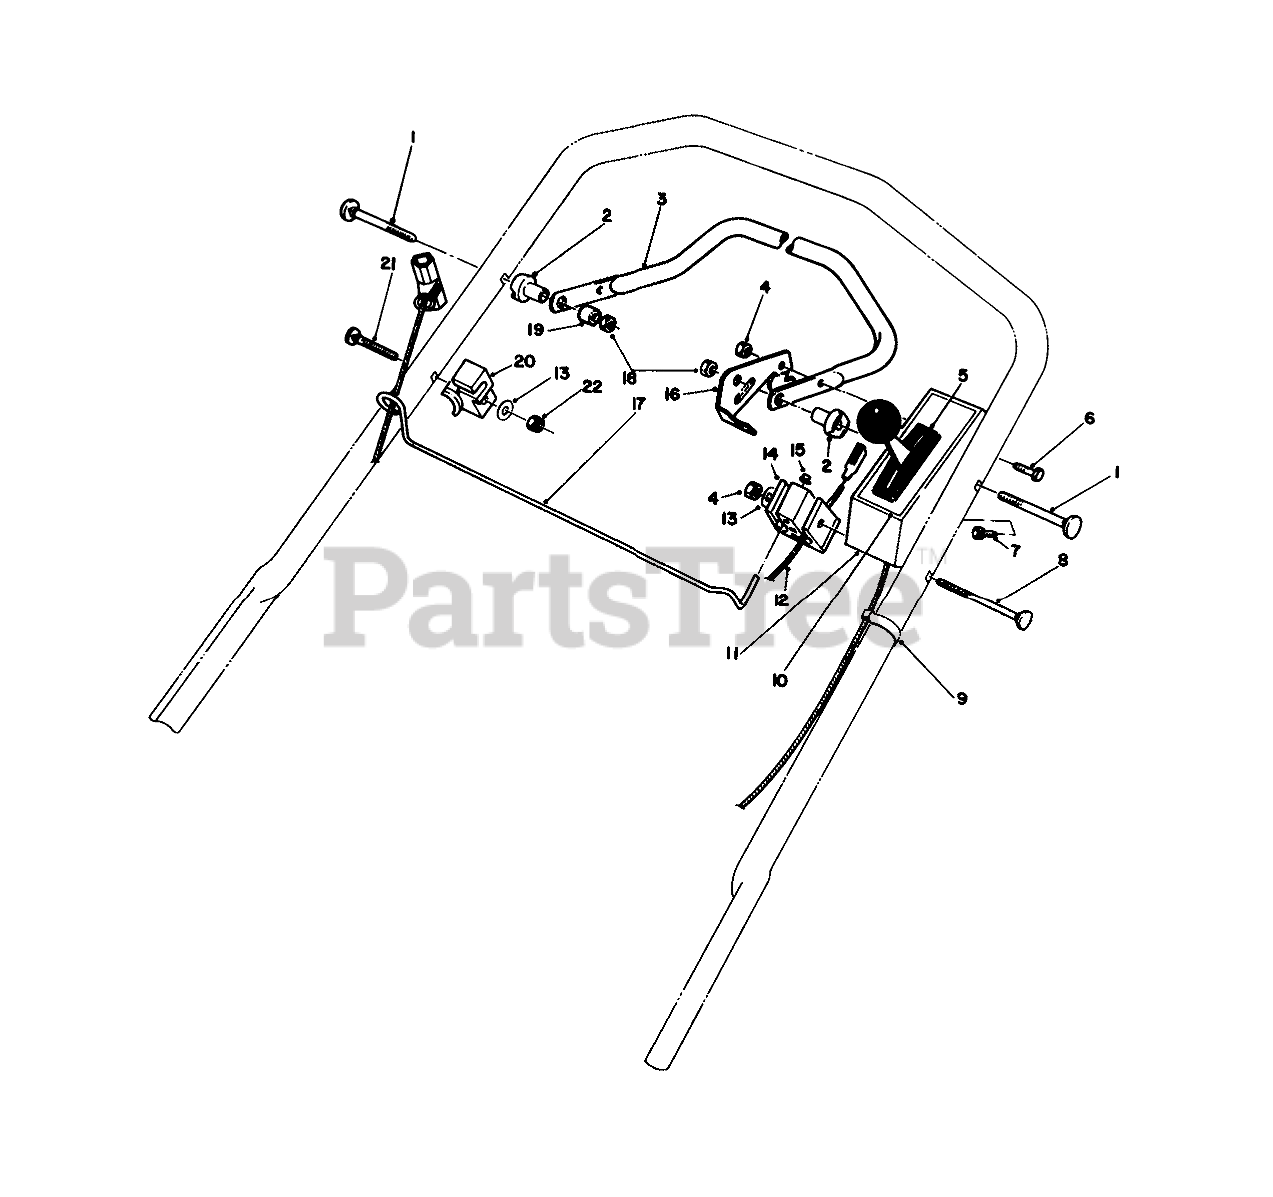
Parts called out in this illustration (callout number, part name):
1	5/16-18 X 2 HNDLE SCREW
2	SPACER-SUPPORT
3	Bar-Control
4	NUT-LOCK, NI
5	THROTTLE CONT-SERVICE
6	SCREW-HH
7	SCREW-HWHTF
8	HANDLE SCREW
9	BOWDEN CLIP
10	Decal-Control Cover
11	CONTROL COVER
12	BRAKE CABLE
13	WASHER-FLAT
14	SUPPORT-CABLE
15	NUT-SPEED
16	LEVER-CONTROL
17	ROPE ROD PLATED
18	NUT-LOCK, NI
19	SPACER-NYLON
20	ROD CATCH
21	SCREW-HANDLE
22	NUT-HEX
